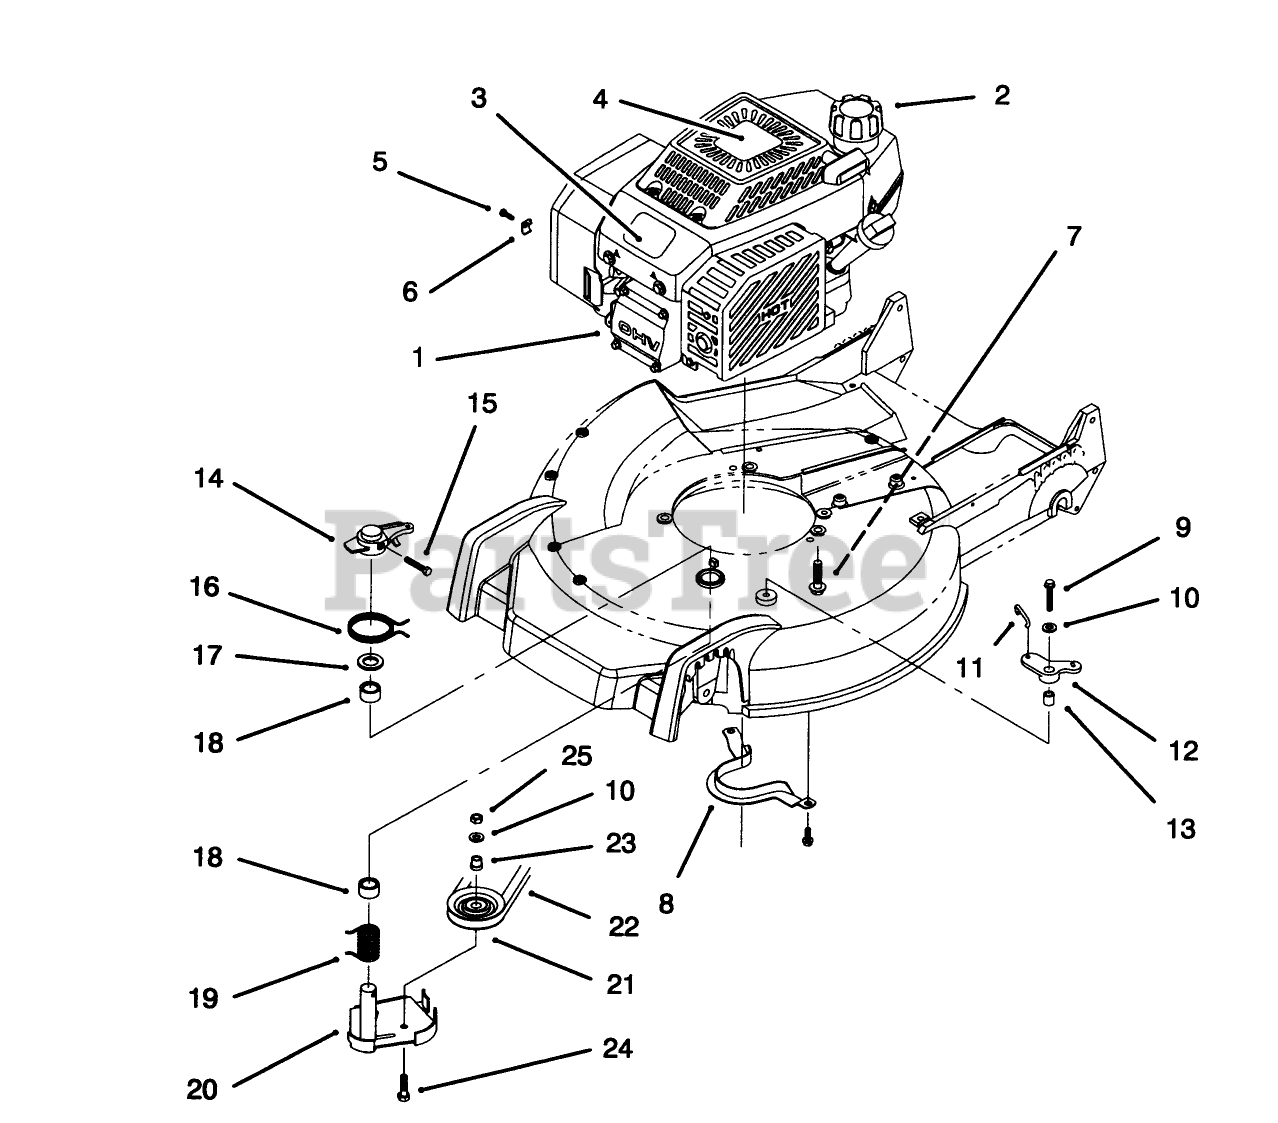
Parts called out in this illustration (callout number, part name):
1	ENG ASM/GTS 150 KE BBC
2	GAS CAP ASM
5	SCREW-CLAMP
6	CLAMP-CASING
7	SCREW-HWH
9	SCREW-HH
10	WASHER-PLAIN
11	LINK-CONTROL
12	BELLCRANK
13	SLEEVE-BELLCRANK
14	LEVER
15	SCREW-HH
16	SPRING-TORSION
17	WASHER
18	BEARING
19	SPRING-TORSION
22	V-BELT
23	HUB-PULLEY, IDLER
24	SCREW-HH
25	NUT-LOCK, NI
